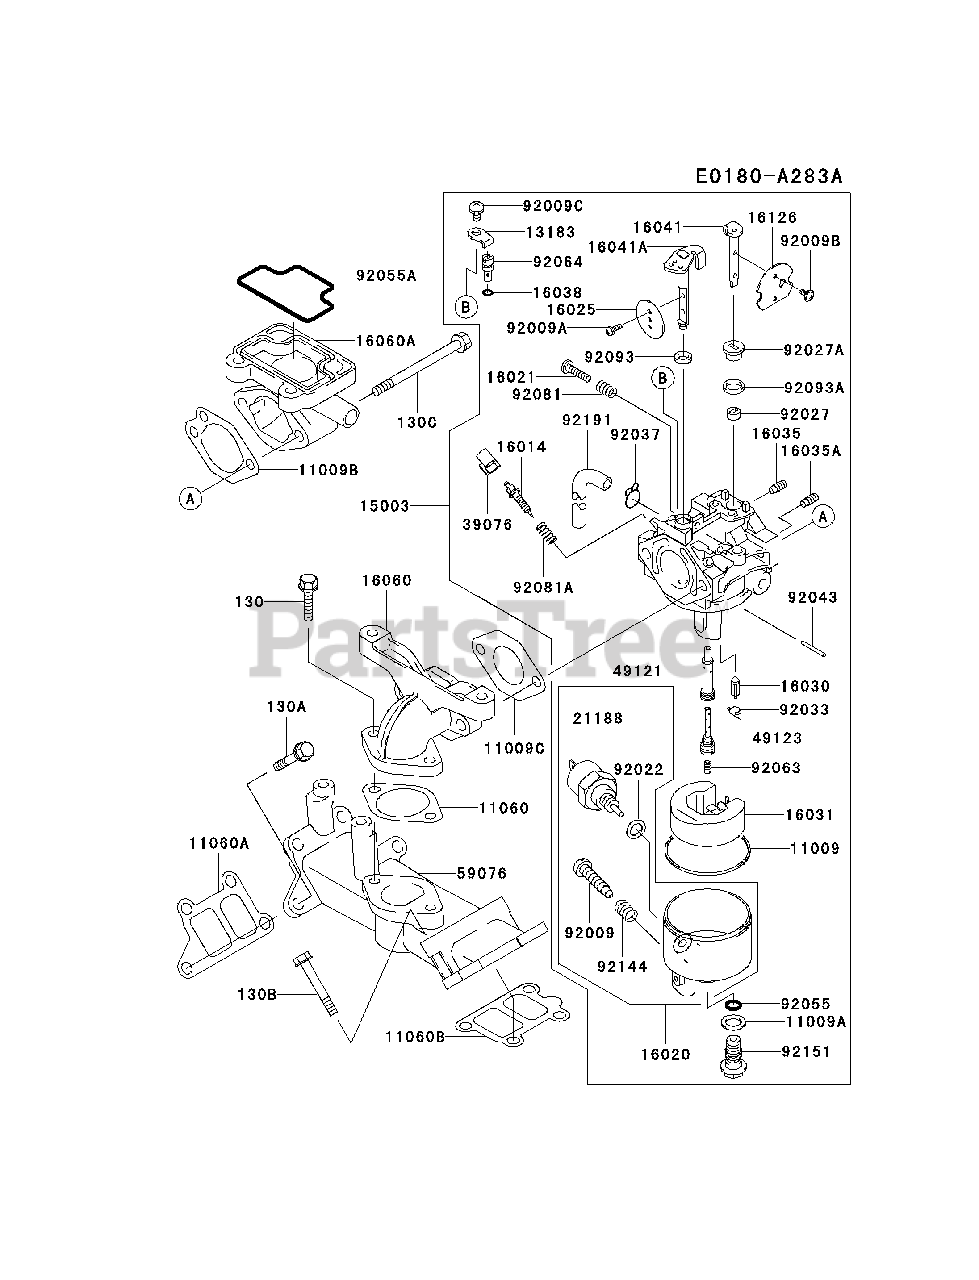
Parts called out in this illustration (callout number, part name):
130	BOLT-FLANGED
130A	BOLT-FLANGED
130B	BOLT-FLANGED
130C	BOLT-FLANGED
92191	TUBE,6.5X9.5X350
